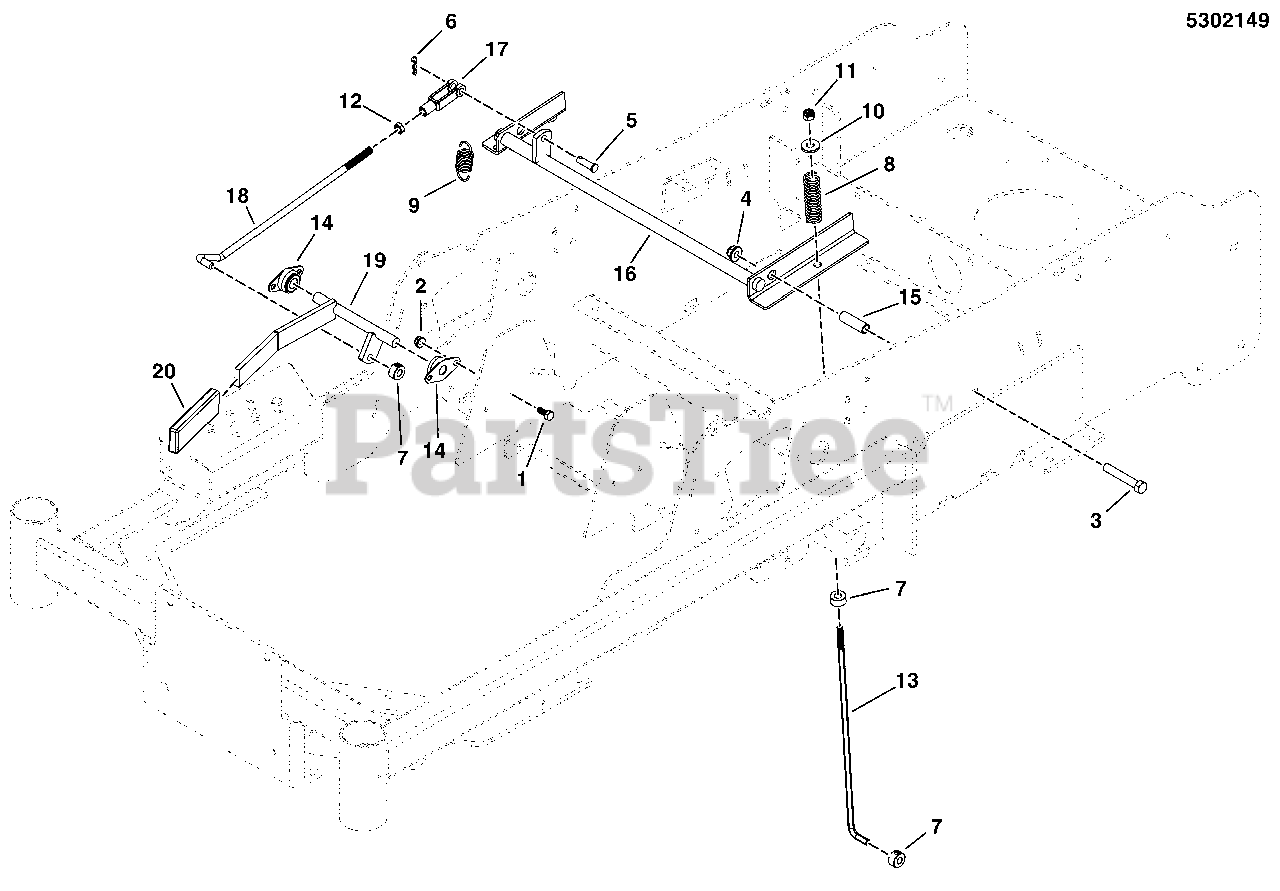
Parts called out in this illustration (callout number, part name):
1	BOLT,1/4-20X5/8
2	NUT, 1/4-20 HEX NYLOCK FLANGE (5025391)
3	BOLT, 3/8-16 X 2-1/4 GD5 YZ
4	NUT, 3/8-16 HEX NYLOCK FLANGE
5	PIN, CLEVIS, 5/16 X 1 YZ
6	PIN, HAIR, .0585 X 1-1/8, 1/4 EYE, YZ
7	COLLAR, 5/16" SET
8	SPRING, COMPRESSION
9	SPRING; CLUTCH HANDLE
10	WASHER, 5/16 USS
11	NUT, 5/16-24 HEX NYLON LOCK
12	NUT, 5/16-24 JAM
13	ROD, BRAKE CTRL, LOWER - CONZ
14	BEARING, 1/2" FLANGED
15	SPACER, .38 X .50 X 1.56
16	WELD, BRAKE SHAFT - BLK
17	CLEVIS, 5/16-24, STEEL
18	ROD, PULLER ROD
19	WELD, BRAKE SHAFT, HANDLE - BLK
20	GRIP, FOAM, 1/4" X 1
